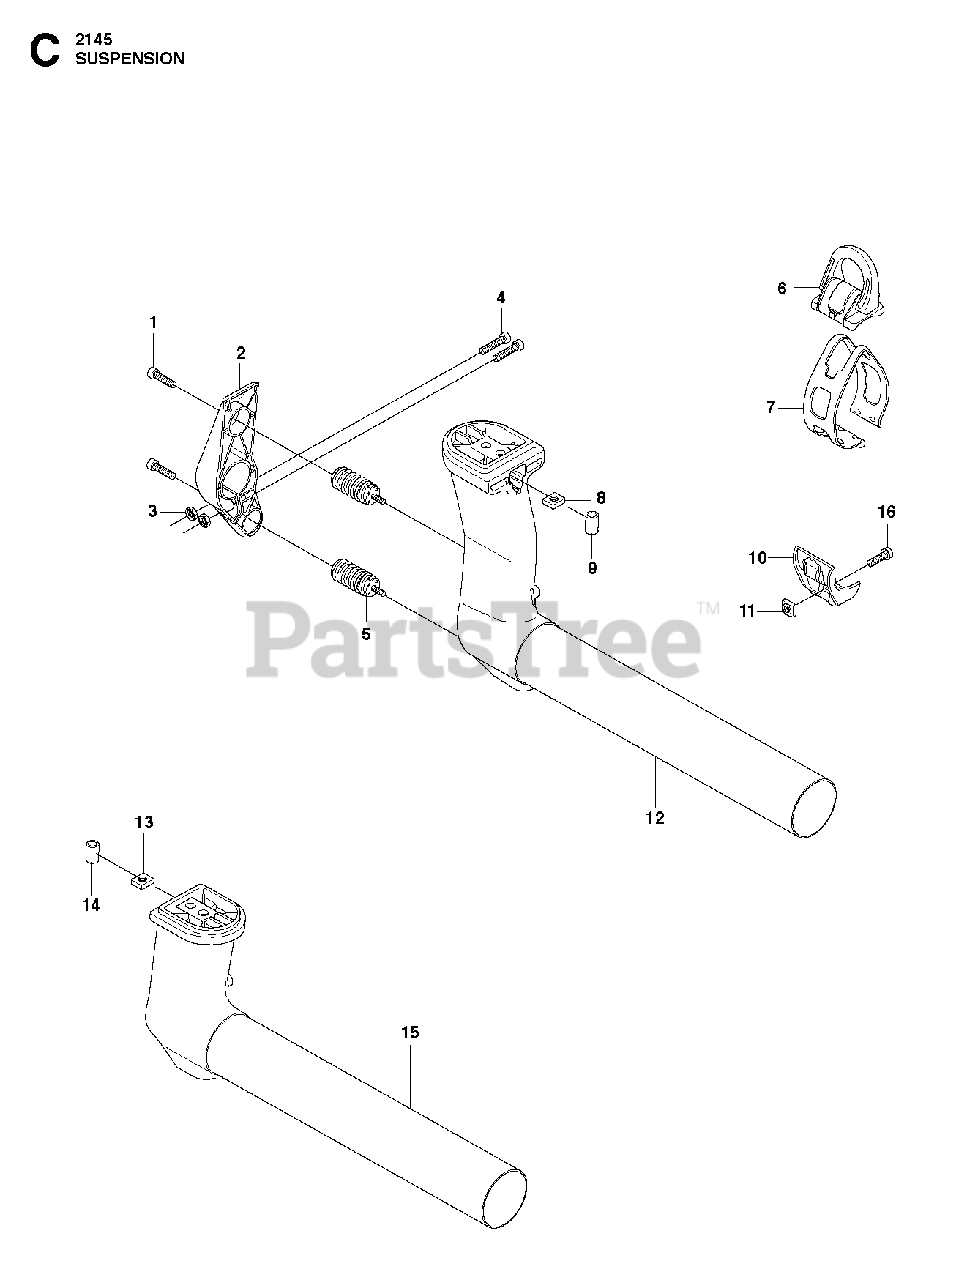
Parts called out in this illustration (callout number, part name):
6	HARNESS HANGER LOOP
10	BRACKET, LOWER HANGER
11	SQUARE NUT M5
